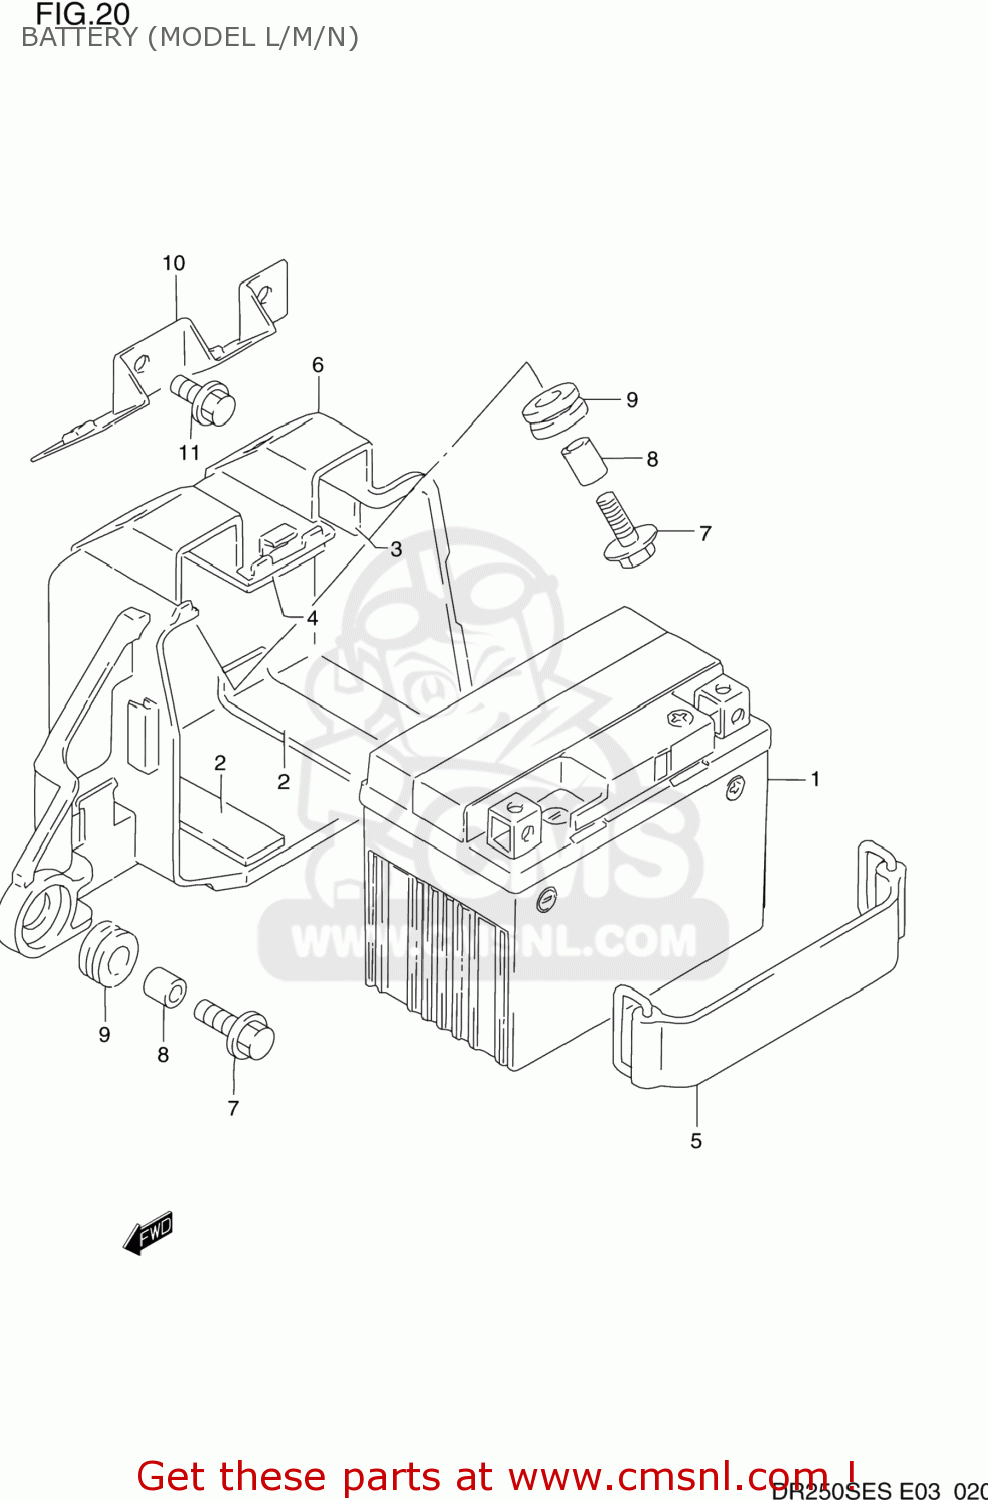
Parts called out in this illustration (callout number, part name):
1	BATTERY ASSEMBLY
2	PROTECTOR,BATTERY
3	PROTECTOR,BATTERY
4	PROTECTOR,BATTERY
5	BAND
6	HOLDER,BATTERY
7	BOLT(6X20)
8	SPACER
9	CUSHION
10	PLATE COMP,BATTERY HOLDER
11	BOLT
